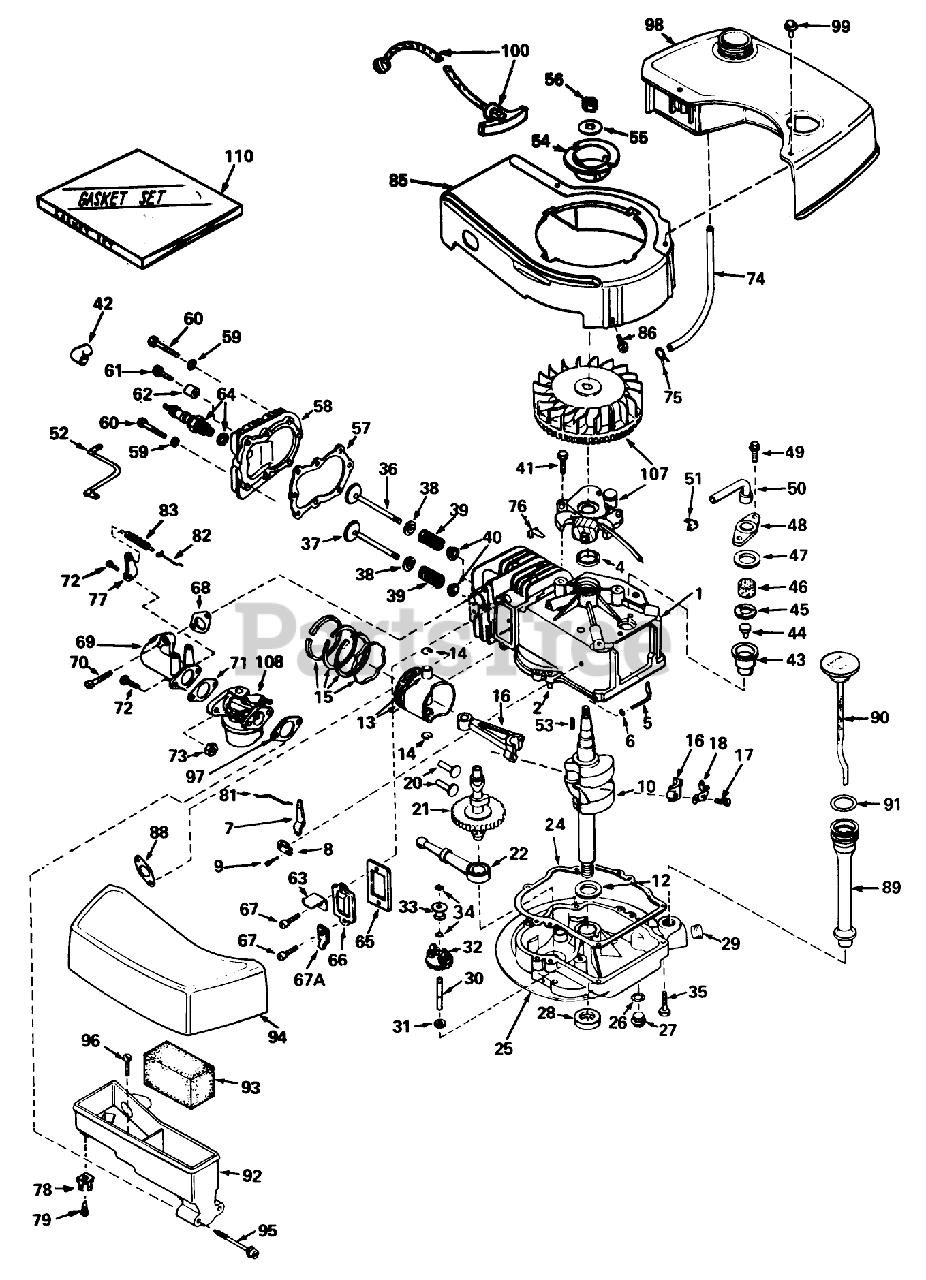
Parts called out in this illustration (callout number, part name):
1	Cylinder Assembly (Incl. Nos. 2, 4 87)
2	Pin-Dowel
4	Seal-Oil
5	Rod, Governor (Incl. No. 36)
6	Washer-Flat
7	Governor Lever
8	Clamp-Lever, Governor
9	Screw
10	Crankshaft
12	Washer-Thrust
13	Piston Pin Assembly (Incl. 2 of No. 14)(Std.)
13	Piston Pin Assembly (Incl. 2 of No. 14)(.010 Oversize)
13	Piston Pin Assembly (Incl. 2 of No. 14)(.020 Oversize)
14	Ring-Retaining, Piston Pin
15	Ring Set-Piston Std.
15	Ring Set-Piston .010 oversize
15	Ring Set-Piston .020 oversize
16	Rod Assembly, Connecting (Incl. Nos. 17 18)
17	Connecting Rod Bolt
18	Plate Lock
20	Lifter-Valve
21	Camshaft(Mech.Comp. Release)
22	Oil Pump ASM
24	Gasket, Mounting
25	Flange Assembly, Mounting (Incl. #27, 28, 29 30)
26	Gasket-Oil Drain
27	Plug Oil Drain
28	Seal-Oil
29	Plug Oil Drain
30	Shaft-Governor
31	Washer-Flat
32	Gear Assembly, Governor
33	Spool, Governor
34	Ring-Retaining
35	Screw (1/4-20 x 1-1/4)
36	Valve, Intake (Incl. Ref. #38, 39 40) (Std.)
36	Valve, Exhaust (1/32" Oversize) (Incl. Nos. 8, 9 10)
37	Valve, Exhaust (Standard) (Incl. Nos. 8, 9 10)
37	Valve, Exhaust (1/32" Oversize) (Incl. Nos. 8, 9 10)
38	Cap-Upper Valve Spring
39	Spring-Valve
40	Cap-Valve, Spring
41	Screw
42	Cover-Spark Plug
43	Body Breather Tube
44	Valve Check
45	2000A37 WIZARD ROTA
46	Element-Breather
47	Gasket-Breather
48	Cover Breather
49	Screw, Hex Hd. w/Conical
50	Tube, Breaker
51	Clip, Breather
52	Wire, Ground
53	Key Flywheel
54	Pulley Starter
55	Washer
56	Hex Nut
57	Oil Fill Tube
58	Head Cylinder
59	Washer
60	Screw
61	Screw Hex Hd. Cap
62	Space
63	Retainer Clip
64	Plug, Spark (J17LM or equiv.)
65	Gasket-Breather
66	Cover-Valve
67	Screw
67A	Terminal
68	Gasket, Intake
69	Pipe, Intake
70	Screw (1/4-20 x 1)
71	Gasket-Carburetor
73	Nut and Lock Washer (1/4-28)
74	Line, Fuel
75	Clamp-Line, Fuel
76	Clip-Wire
77	Lever-Adjusting, R P M
78	Terminal
79	Screw
81	Link Governor
82	Link Governor Spring
83	Spring Governor
85	53024/VAR.GT O/P W/
86	Screw
88	Gasket Exhaust
89	Tube, Oil Filler
90	Dipstick, OiI (Incl. No. 91)
91	O-Ring
92	Body Air Cleaner
93	Filer, Air
94	Cove, Air Cleaner
95	Screw Fil Hd.
96	Screw, Hex Hd.
97	Gasket-Air Cleaner
98	Tank Fuel
99	Screw (10-32 x 35/64)
100	Rope Assy., Starter
107	Magneto
108	Carburetor
110	53024/VAR.16HP O/P
